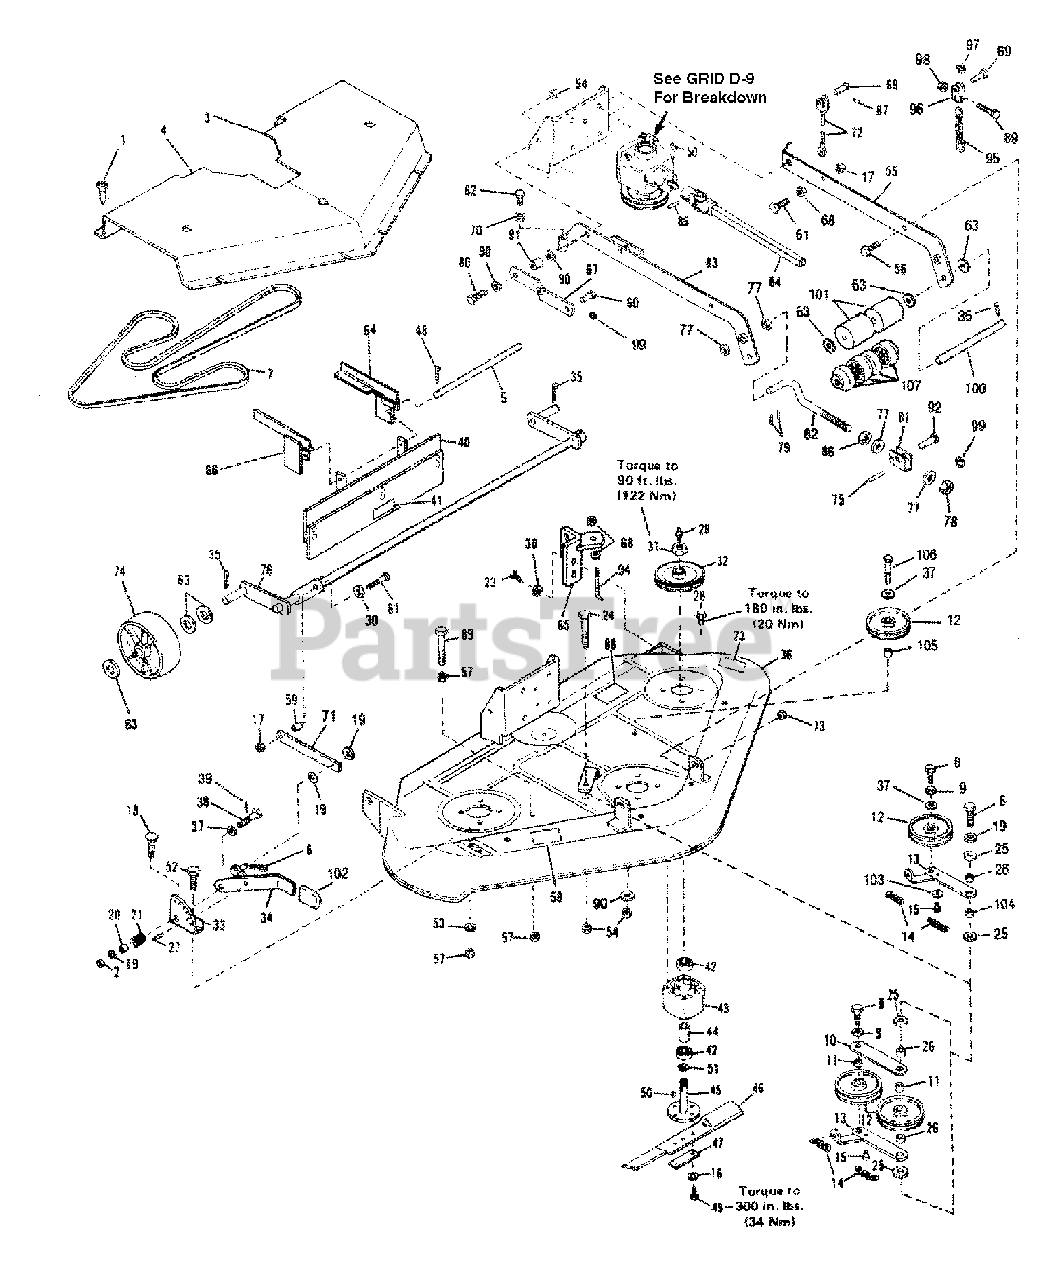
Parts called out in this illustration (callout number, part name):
1	Self Driving Screw, 10-24 x 5/8
2	Lock Nut, 1/2-13
3	Belt Cover, LH
4	Belt Cover, RH
6	Hex Screw 1/2-13 x 1-1/2
7	V-Belt (137")
8	Hex Screw, 1/2-13 x 1-5/8
9	Lockwasher, 1/2
10	Idler Arm
11	Spacer
12	Idler Pulley
13	Idler Arm
14	Extension Spring
15	Wear Button
16	Lockwasher, 3/8
17	Lock Nut, 3/8-16
18	Carriage Bolt, 5/16-18 x 3/4
19	Flat Washer, 1/2
20	Spacer
21	Spring
22	Hex Screw 3/8-16 x 1
23	Warning Decal
24	Capscrew, 1/2-13 x 2-3/4
25	Thrust Washer
26	Bearing Sleeve
27	Drive Pin, 5/16-18 x 3/4
28	Flange Screw, 5/16-18 x 3/4
29	Grease Fitting
30	Flat Washer 3/8
31	Locknut, 3/4-16
32	Blade Sheave
34	Handle Assembly
35	Cotter Pin, 1/8 x 1
36	Mower Base Assembly
37	Flat Washer, 1/2
38	Special Screw
39	Roll Pin, 3/16 x 7/8
40	Guard Assembly
41	Caution Decal
42	Ball Bearing
43	Spindle Housing
44	Spacer
45	Shaft Assembly
47	Plate
48	Cotter Pin, 3/32 x 1/2
49	Capscrew, 3/8-24 x 1
50	Woodruff Key, 3/16 x 3/4
51	Flat Washer, Special
52	Hex Capscrew, 5/16-18 x 3/4
53	Flat Washer, 5/16
54	Lock Nut, 1/2-13
55	Support Ass'y LH
56	Flange Screw 3/8-16 x 1
57	Top Locknut, 5/16-18
58	Decal, Mower
59	Spacer
60	Clevis Pin
61	Capscrew, 3/8-16 x 1-1/2
62	Fl. Screw 3/8-16 x 2
63	Flat Washer, 5/8
64	R.H. Stop Assembly
65	Shaft Support Ass'y
66	L.H. Stop Assembly
67	Drag Link
68	Jam Nut 3/8-16
69	Clevis Pin
70	Hex Nut, 3/8-16
71	Link, Connecting
72	Lift Cable
73	Flange Nut 3/8-16
74	Gage Wheel
75	Roll Pin
76	Pivot Shaft Ass'y
77	Flat Washer
78	Hex Nut 3/4-10
79	Cotter Pin, 1/8 x 1-1/4
80	Hex Screw 1/2-13 x 1-3/4
81	Hitch Bracket
82	Hitch Link
83	Mower Hanger
84	Drive Assembly
85	Roll Pin, 3/16 x 1-1/2
86	Hex Nut 3/4-10
87	Cotter Spring
88	Belt Drive Decal
89	Hex Screw 5/16-18 x 1-1/4
90	Flat Washer, 1/2
91	Spacer
92	Clevis Pin
95	Chain
96	Clevis
97	Circle Cotter Ring
98	Lock Nut
99	Cotter Spring
100	Roller Shaft
101	Roller
102	Grip
103	Flat Washer
104	Spacer
105	Spacer
106	Hex Screw 1/2-13 x 2
107	Roller
